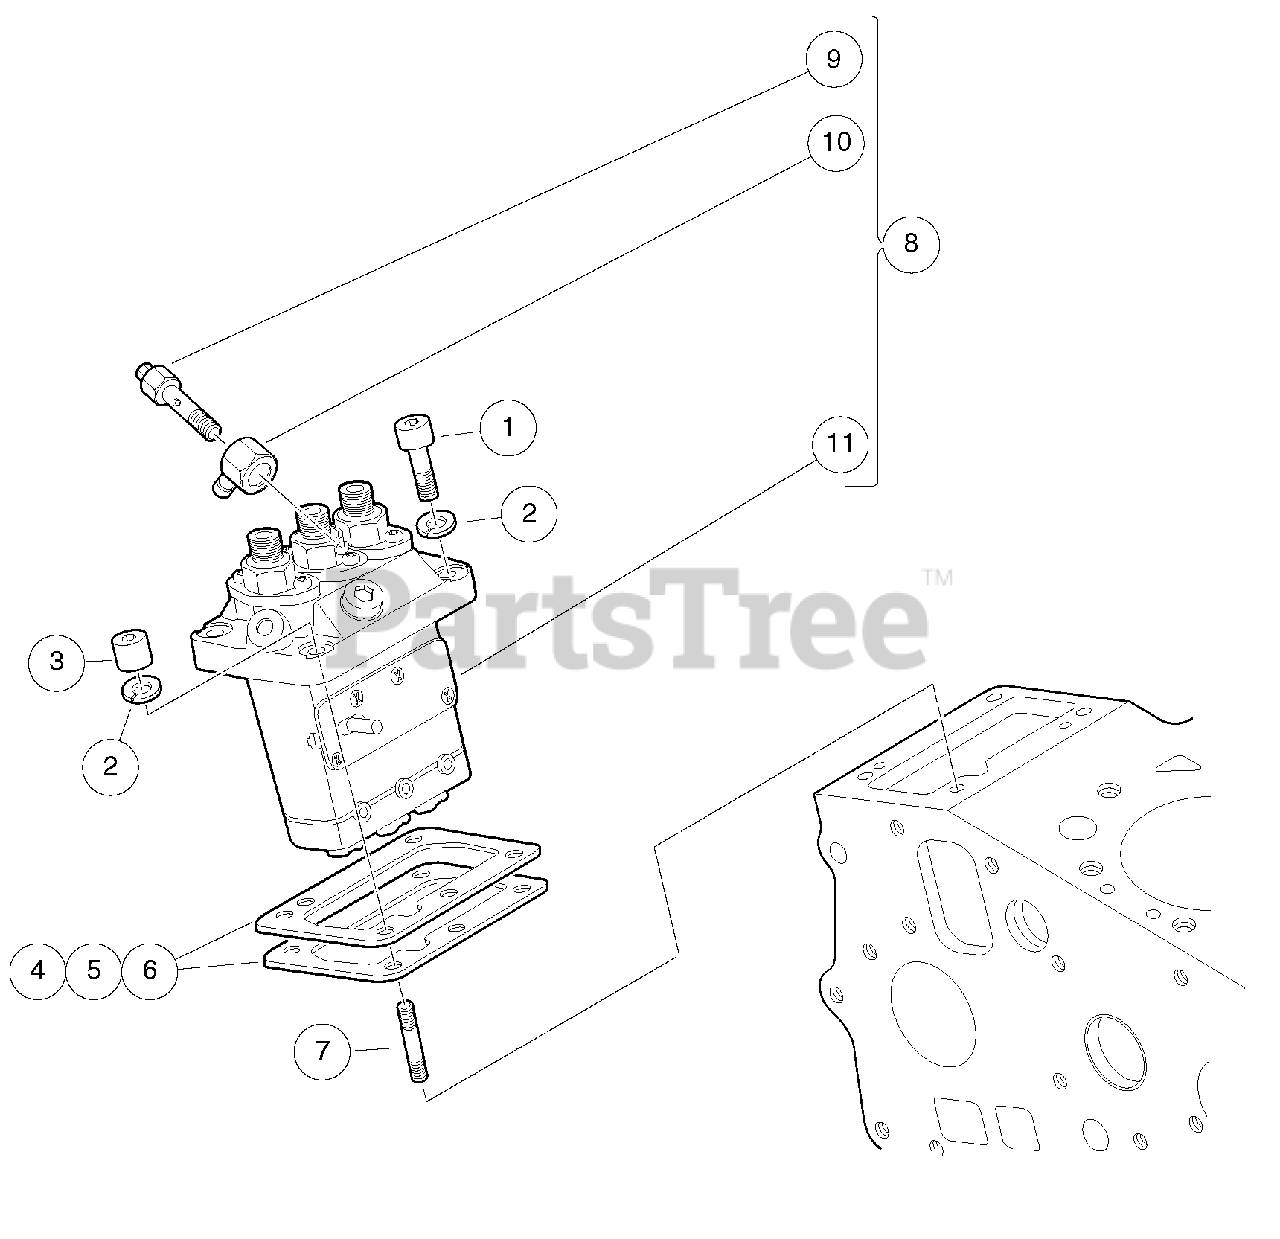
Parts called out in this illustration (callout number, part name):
1	Bolt, Hex-Head, M5 X 0.75
2	Washer, Spring, M6, D722
3	Nut, Special
4	Shim, Injection Pump, 0.20 mm
5	Shim, Injection Pump, 0.25 mm
6	Shim, Injection Pump, 0.30 mm
7	Stud, M5 X 25
8	Assembly, Fuel Injection Pump
9	Screw, Hollow, D722, Inj Pump
10	Joint, Eye
11	Pump, Injection
